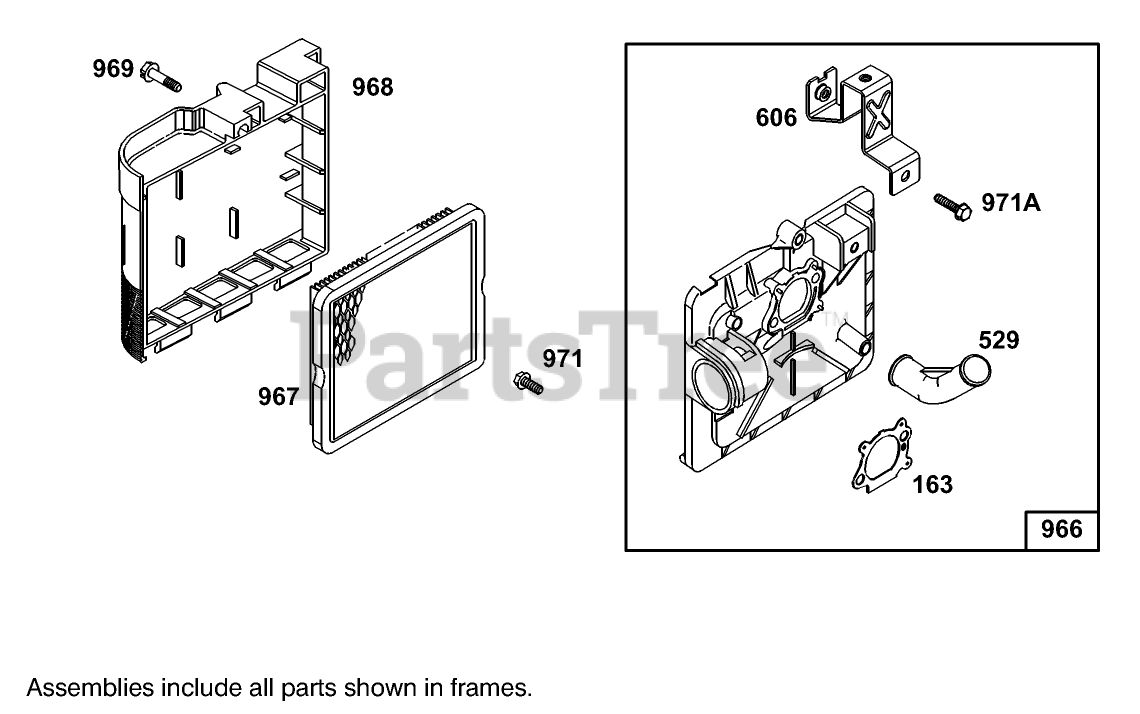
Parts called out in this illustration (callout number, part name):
163	Gasket-Cleaner, Air
529	Grommet
606	Strap-Bracket
966	Base-Primer, Air Cleaner
967	Filter-Air Cleaner, Cartridge
968	Air Cleaner Cover
969	Screw-Cover Mt.
971	Screw-Air Cleaner
971A	Screw-Hex.
